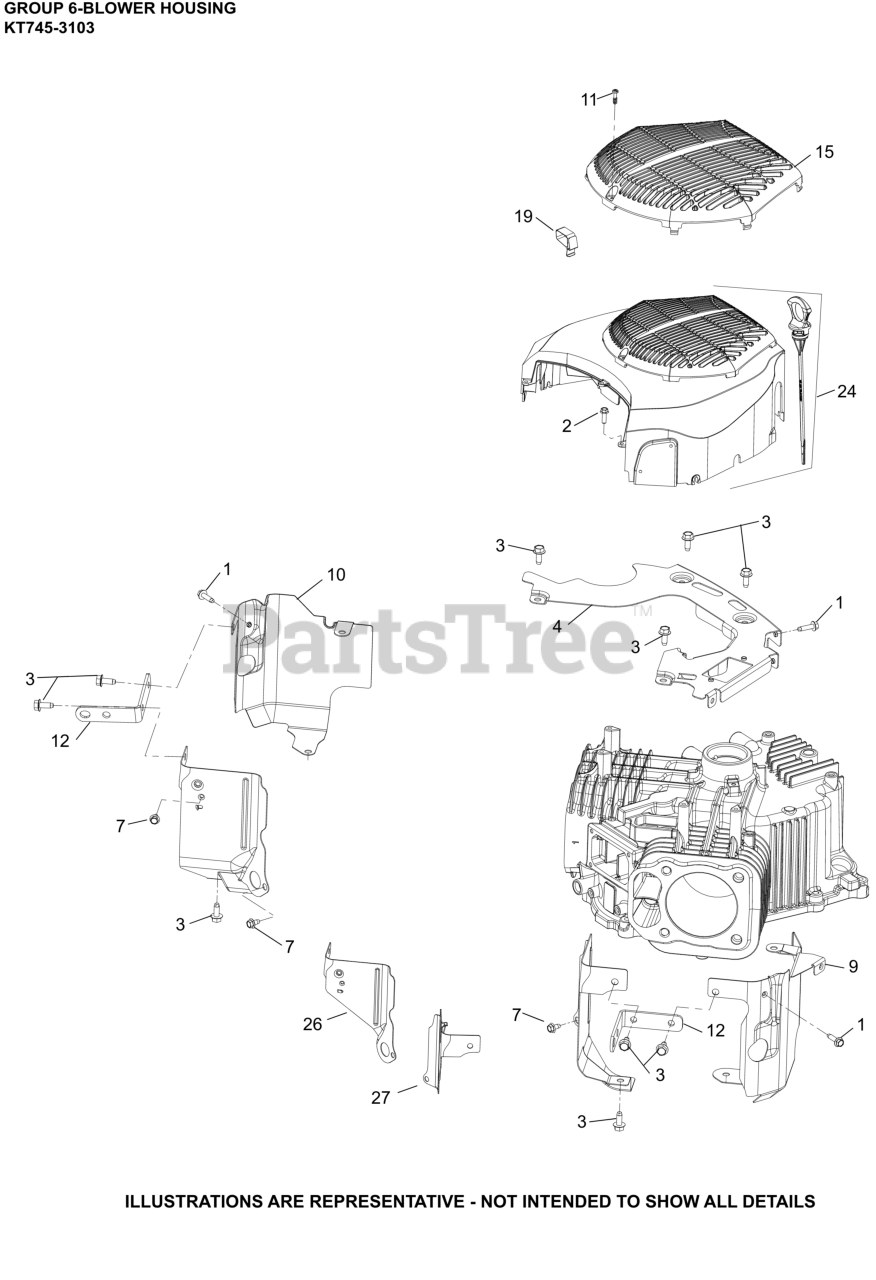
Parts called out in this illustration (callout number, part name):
1	SCREW, THD FRM-USE 25 086 473-S
2	SCREW, HI-LOW
3	SCREW, THREAD FORMING
4	PLATE, BACKING
7	SCREW, THREAD FORMING
9	BAFFLE, LEFT BARREL
10	BAFFLE, RIGHT BARREL
11	SCREW, M5-2.42 (PT) THREAD
12	STRAP, LIFTING
15	GUARD, FIXED
19	CLIP, BLOWER HOUSING
24	KIT, BLOWER HOUSING
26	BAFFLE, VALLEY #1 CYLINDER
27	BAFFLE, VALLEY #2 CYL-USE 32 063 36-S
